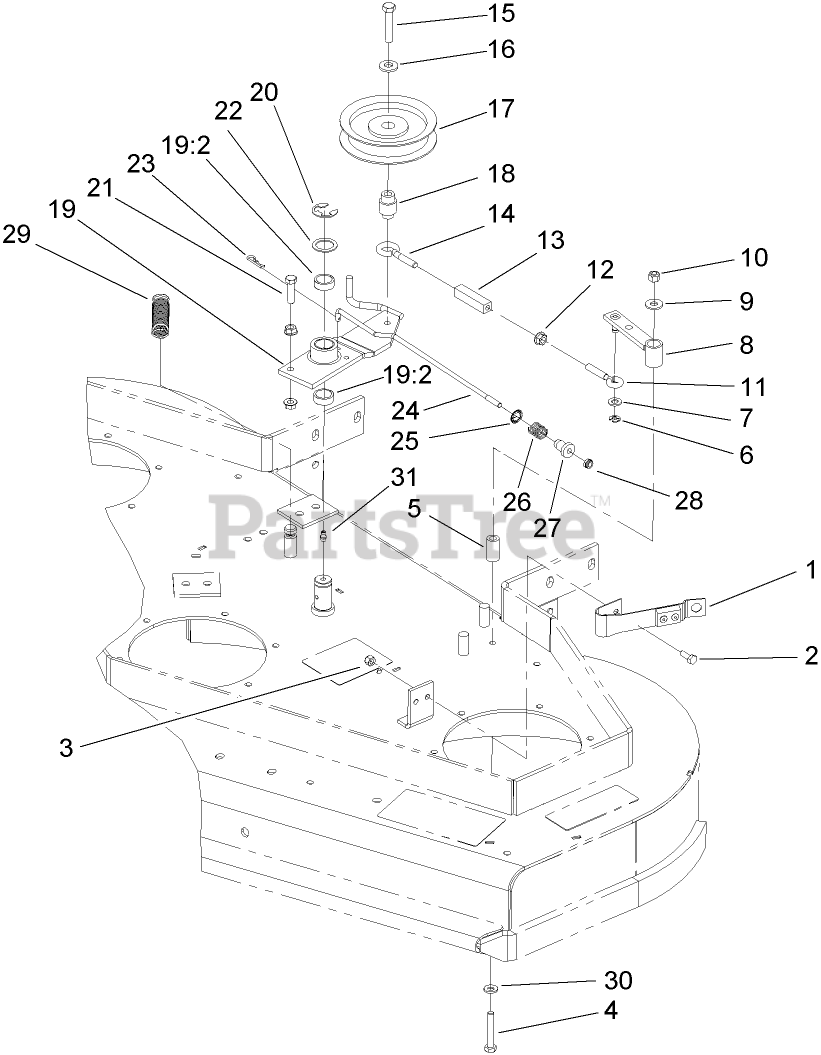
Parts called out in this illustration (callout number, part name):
1	PAD AND SPRING ASM
2	SCREW-HH
3	NUT-LOCK, NI
4	SCREW-HH
5	TUBE-PIVOT
6	RING-RETAINING, EXT
7	WASHER-PLAIN
8	ARM-ASSIST
9	WASHER-FLAT
10	NUT-LOCK, NI
11	EYEBOLT-THREAD, RH
12	NUT-HF
13	BODY-TURNBUCKLE
14	EYEBOLT-THREAD, LH
15	SCREW-HH
16	WASHER-BELLEVILLE
17	PULLEY-IDLER
18	BUSHING-ENGAGEMENT
19	Idler Arm ASM
19:2	SLEEVE-BEARING
20	RING-RETAINING, EXT
21	SCREW-HH
22	WASHER-SPINDLE
23	PIN-COTTER
24	ROD-BRAKE
25	RING-PUSH ON
26	SPRING-COMPRESSION
27	SPACER-FLANGED
28	NUT-LOCK, NI
29	SPRING-EXTENSION
30	WASHER-SPRING
31	FITTING-GREASE
